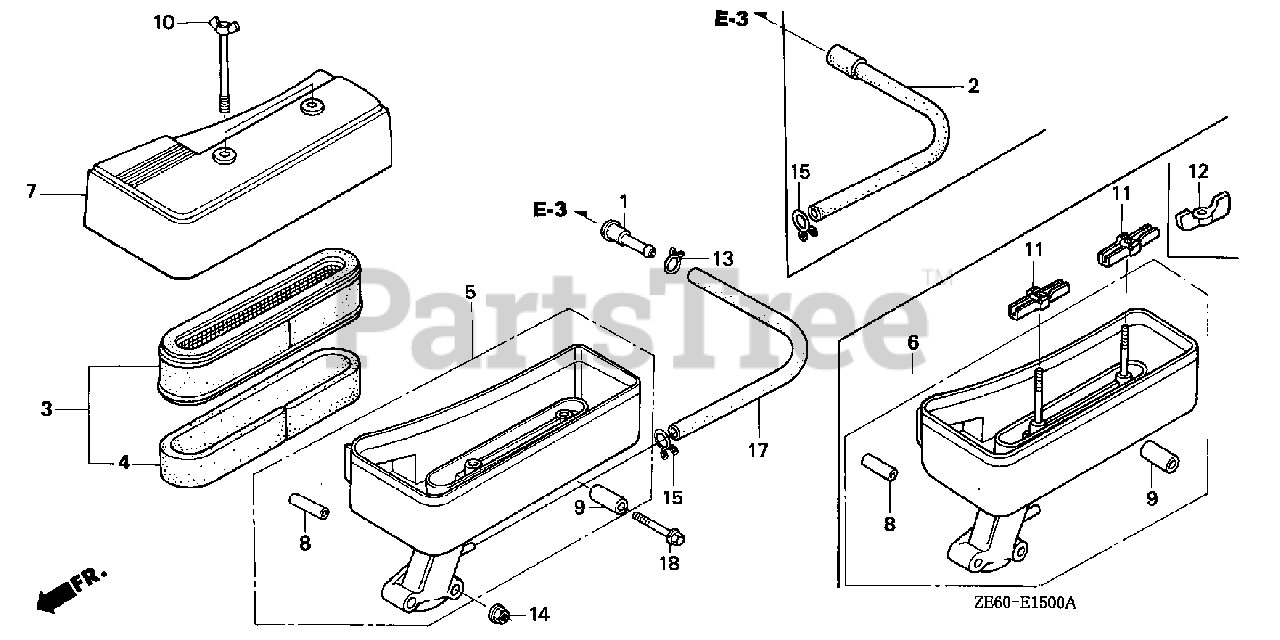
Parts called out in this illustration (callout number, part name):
2	TUBE, BREATHER (180MM)
3	ELEMENT, AIR CLEANER
4	FILTER (OUTER)
6	HOUSING, AIR CLEANER
7	COVER, AIR CLEANER
8	COLLAR, AIR CLEANER
9	COLLAR B, AIR CLEANER
11	NUT, AIR CLEANER COVER (DACRO COATING)
11	WINGNUT (6MM) (BLACK)
13	CLIP, TUBE
14	NUT, FLANGE (6MM)
15	CLIP, TUBE (B12)
18	BOLT, FLANGE (6X35)
